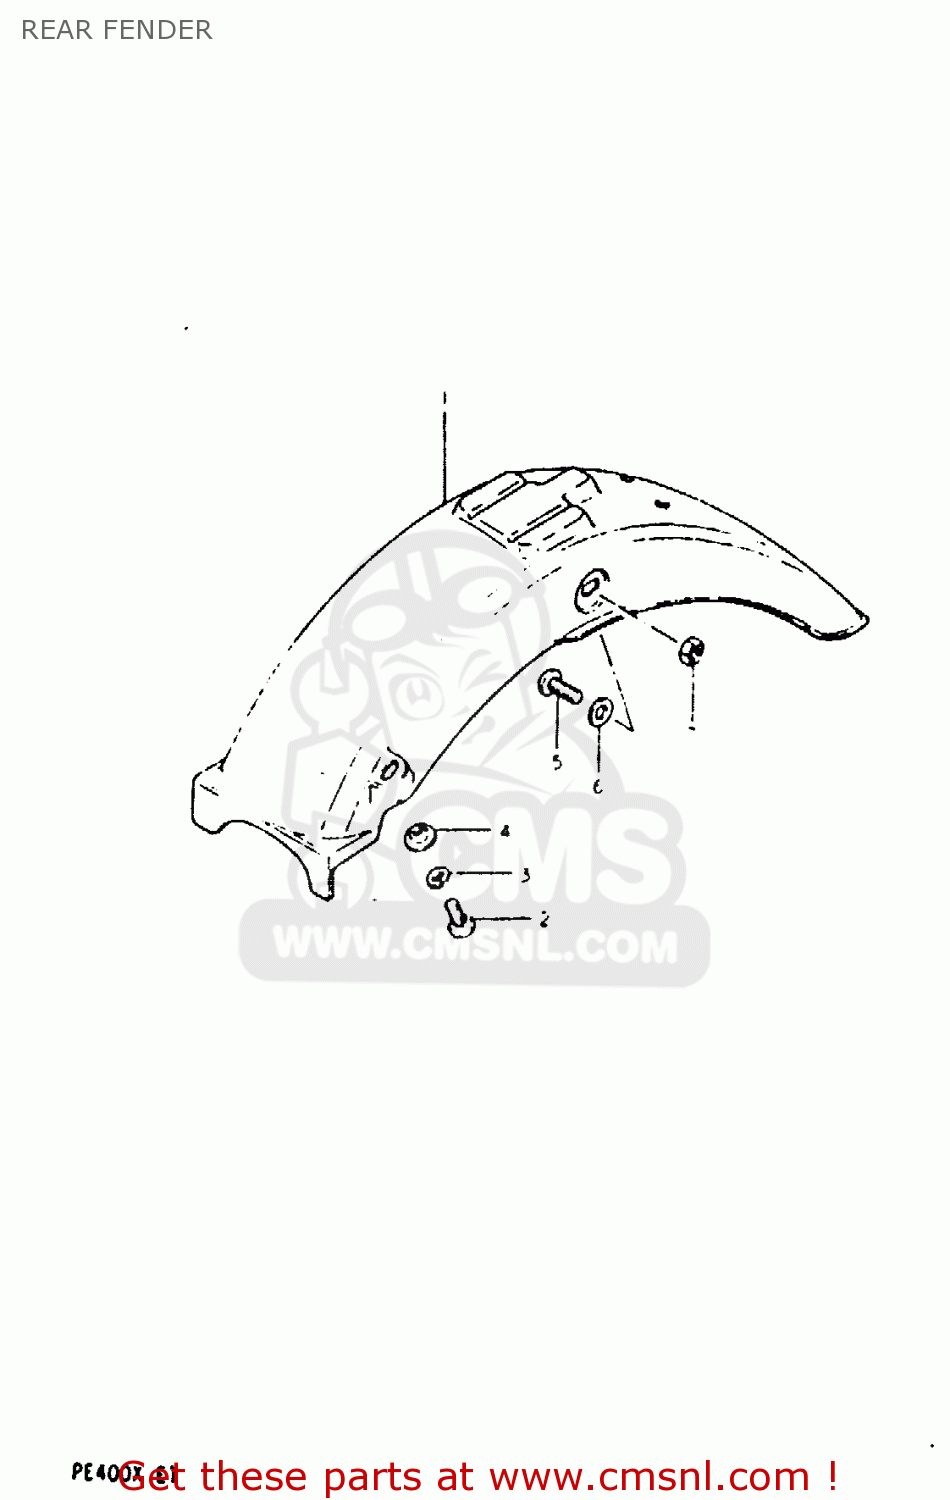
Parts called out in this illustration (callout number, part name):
1	FENDER, REAR (YELLOW)
2	BOLT
3	LOCK WASHER
4	WASHER
5	SCREW
6	WASHER (6.5X20X1.2)
7	NUT
